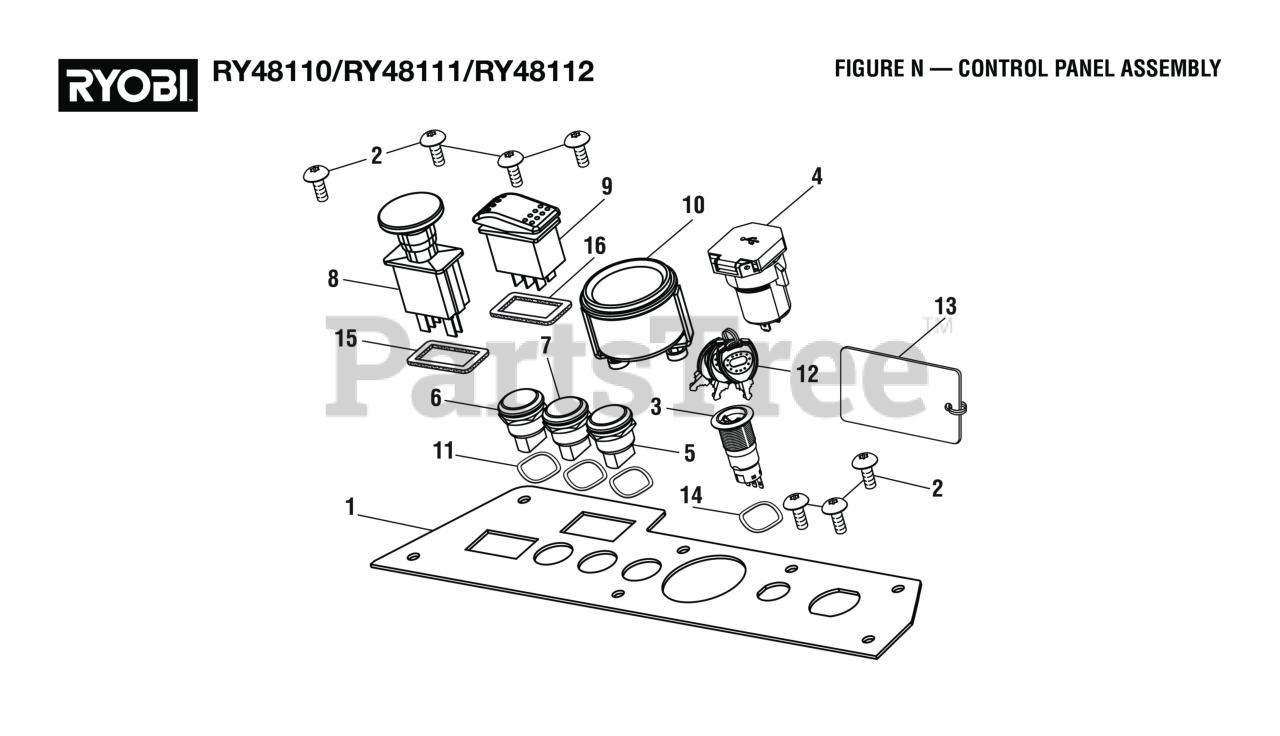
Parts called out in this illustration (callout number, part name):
1	Face Plate
2	Screw (M6 x 10 mm, Soc. Button Hd.)
3	Switch Key Module
4	USB Module
5	Light Switch
6	Cruise Button
7	Reverse Mow Operation Button
8	Power Take Off Button (PTO)
9	Toggle Switch
10	Gauge Module
11	Wavy Washer
13	Watch For Kids, Keychain Label
14	Wavy Washer
15	Rubber Gasket
